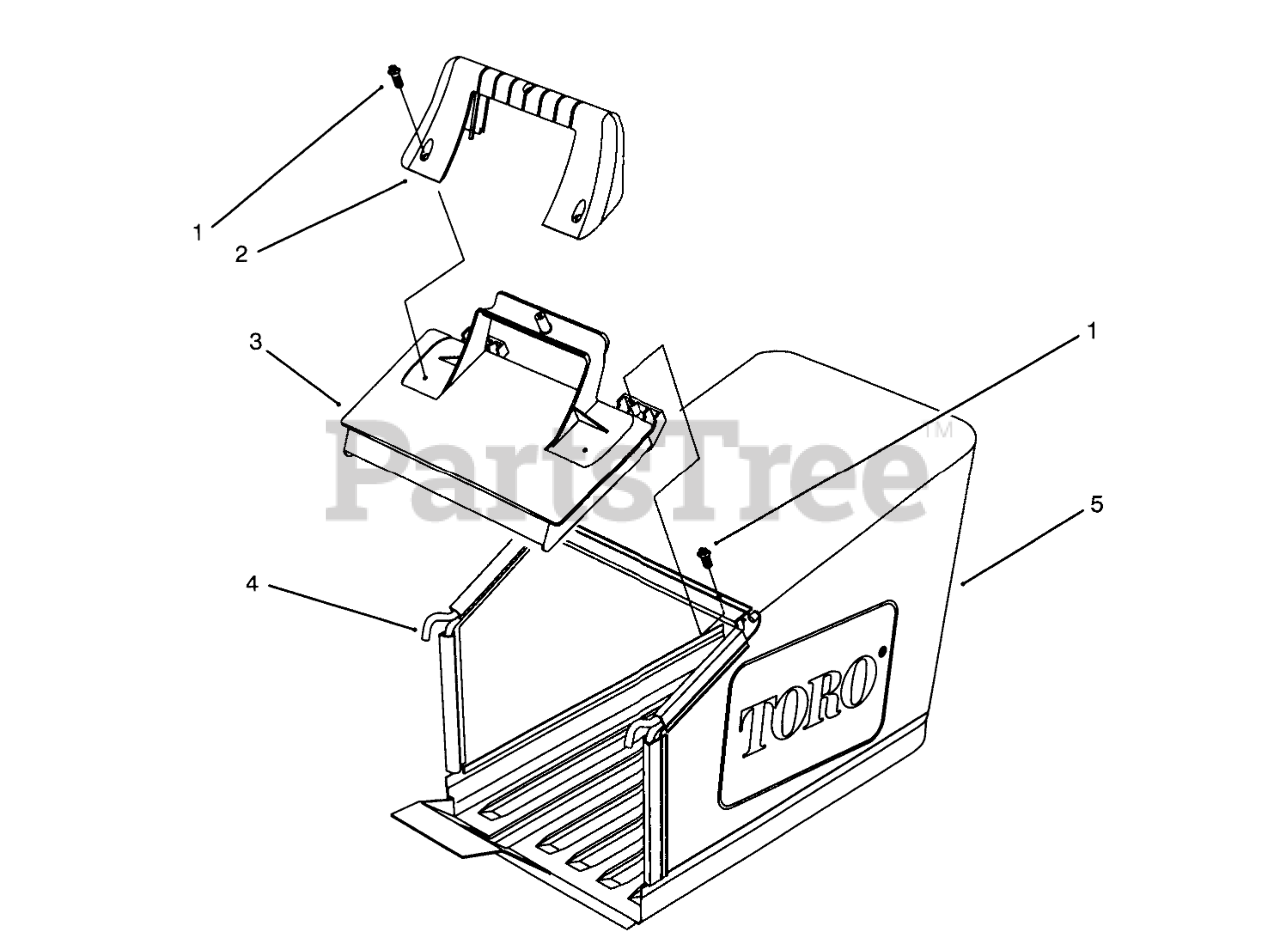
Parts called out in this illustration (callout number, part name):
1	SCREW-PPH
2	HANDLE-DOOR
3	DOOR-BAG
4	Frame
5	BAG-GRASS
